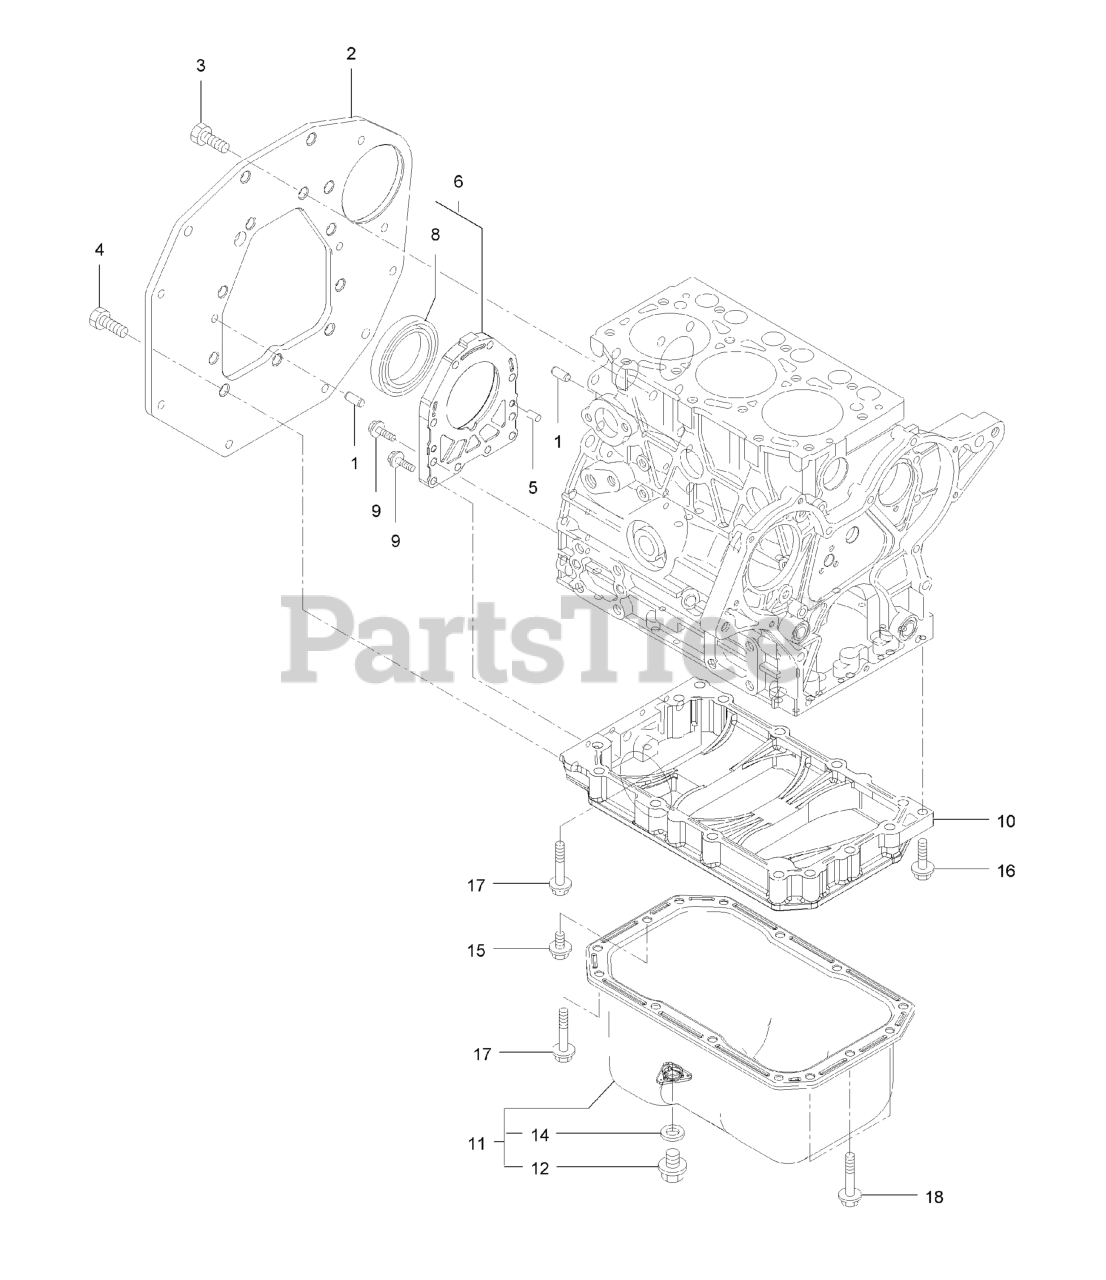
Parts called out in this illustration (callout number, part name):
2	FLANGE-MOUNTING
5	PIN-PARALLEL
6	CASE ASM-OIL SEAL
8	SEAL-OIL
10	SPACER-OIL PAN
11	OIL PAN ASM
14	WASHER-SEAL
